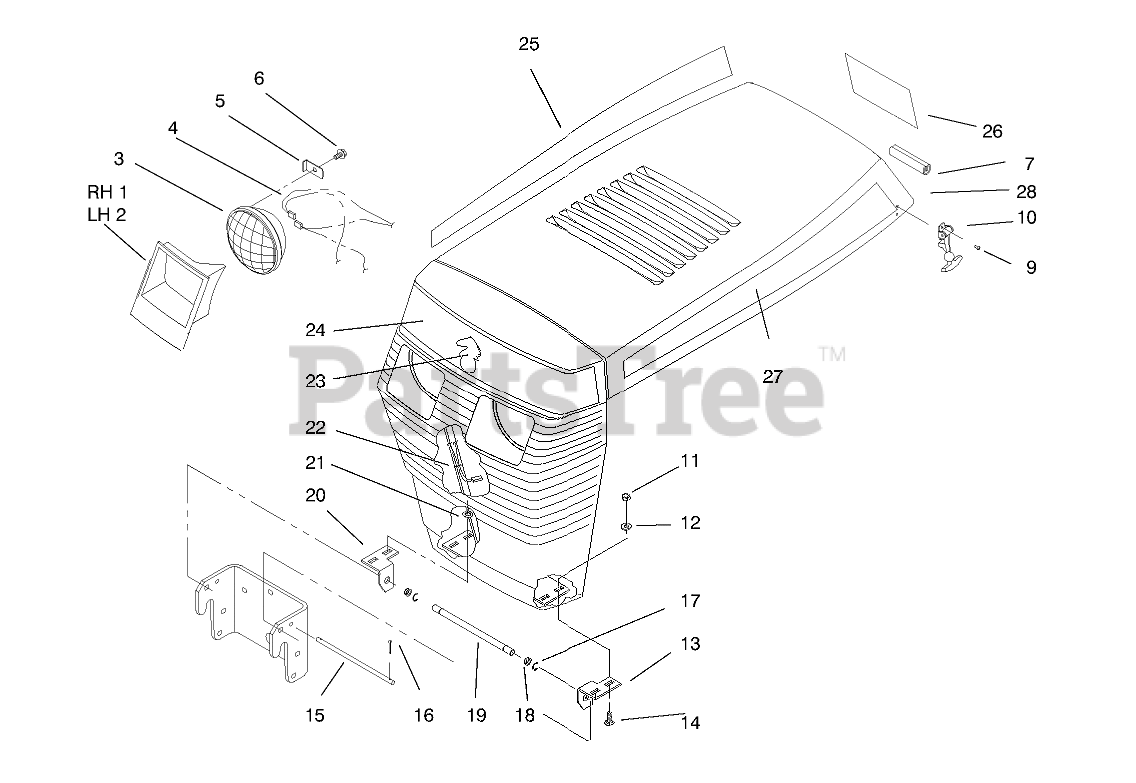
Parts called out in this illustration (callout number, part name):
1	BEZEL-HEADLIGHT, LH
2	BEZEL-HEADLIGHT, RH
3	HEADLAMP
4	LIGHT GROUND WIRE
5	LOCK-HEADLIGHT
6	SCREW-HWH
7	EDGING-CONSOLE
9	RIVET-POP
10	HANDLE ASM
11	NUT-LOCK, NI
12	WASHER-FLAT
13	BRACKET-GRILL, LH
14	SCREW-CARR
15	ROD-HOOD STOP
16	PIN-COTTER
17	BUSHING-NYLINER
18	RING-RETAINING
19	ROD-GRILL PIVOT
20	BRACKET-GRILL, R H
21	WASHER-LOCK, INTERNAL
23	LOGO - HORSEHEAD
24	DECAL-FRONT HOOD, TOP
25	DECAL - RH HOOD TOP
26	DECAL - DANGER
27	DECAL - LH HOOD TOP
28	Hood
